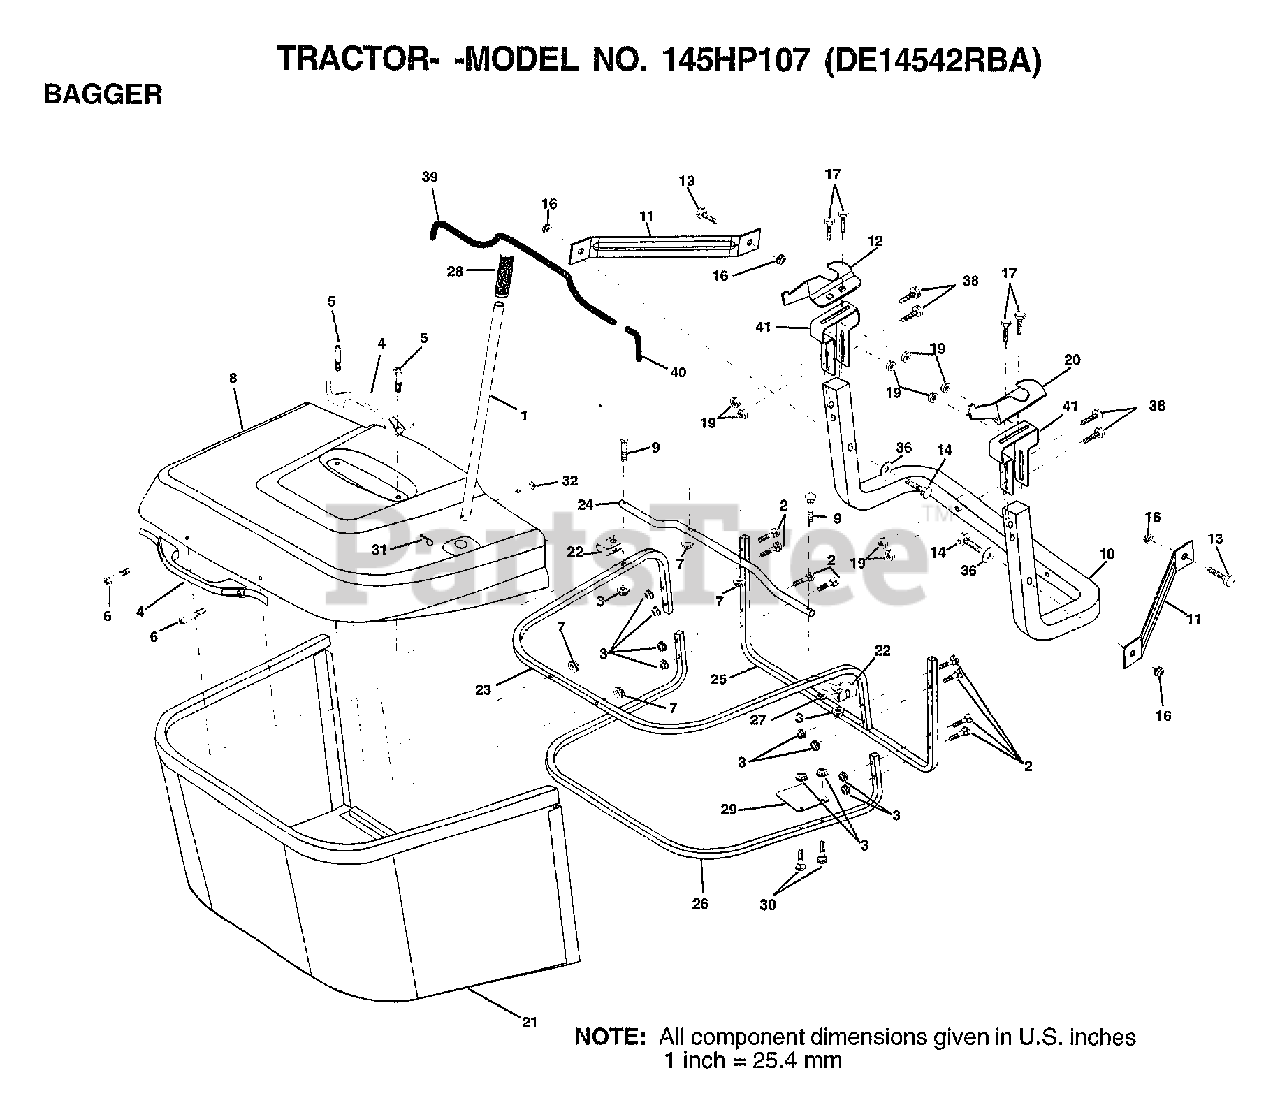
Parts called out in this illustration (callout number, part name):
1	TUBE.HDLE.BAG.CRD
2	BOLT.CARRIAGE.1/4-20X2.0
4	HANDLE BAGGER
5	"SCREW,PAN.HEAD"
7	NUT.WIZ.LOCK
8	COVER.BAGGER.CRD
9	BOLT CARRIAGE
10	TUBE SUPPORT BAGGER CRD
11	BRKT.SUPT.UPPER.BAG.CRD
12	BRACKET HORIZ ADJ BGGR LH CRD
13	BOLT
14	BOLT.HEX.3/8-16X2-1/2
17	BOLT
19	"NUT HEX,LOCK,FLAN"
20	BRACKET HORIZ ADJ BGGR RH CRD
21	BAG.ASM.CRD
22	BRKT.SIDE.BAG.CRD
23	TUBE.UPPER.BAG.CRD
24	TUBE.PIVOT.BAG.CRD
25	TUBE.FT.BAG.CRD
26	TUBE.LOWER.BAG.CRD.
27	BUSHING SNAP BAGGER CRD
28	GRIP.HANDLE.BLACK
29	PLATE.STOP.BAG.HDLE.CRD
30	BOLT.CARRIAGE
31	RETAINER M
32	RIVET.DRILL.1.75
38	BOLT.5/16-18X2.5
41	BRACKET VERT ADJ BAGGER CRD
